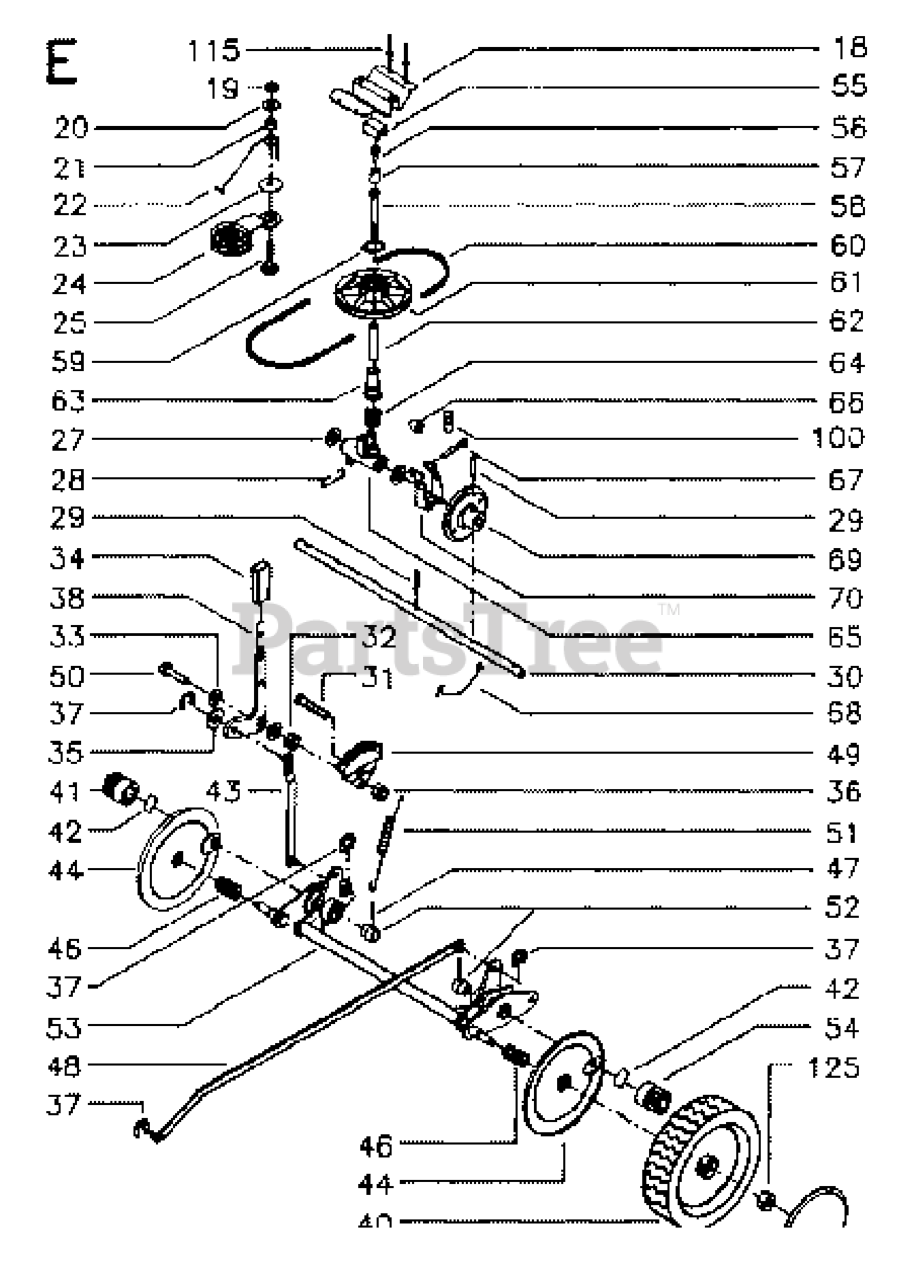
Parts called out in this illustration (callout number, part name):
1	DECK.WELDMENT.54"MS-498
6	COVER.MANDREL.LH.54"20
7	COVER.MANDREL.RH.54.20
8	BOLT.WASHER.ASM.7/16-2
11	BLADE.BAGGING.54"
12	ROD.ANTI.SWAY.48/54"K4
13	SHAFT ASM MANDREL
14	RP.HOUSING.MANDREL.4PT.
16	WASHER
18	BOLT
19	PIN.COTTER.5/16.BOW TI
21	LOCKNUT
24	CAP-SLEEVE LT
25	SPRING, TORSION
26	NUT PUSH M
27	DEFLECTOR
29	ROD.HINGE
30	SCREW, WASHER HEAD
31	WASHER.SPACER.MANDREL
32	PULLEY/MANDREL
33	NUT.FLANGE.LOCK.TOP
39	RB PULLEY.IDLER.4.50/HUB SPEC
43	ARM.IDLER
46	SCREW.1/4-20X5/8
47	RP.BELT.DRIVE.54."2006
49	NUT LOCK FLG 3/8-16 UNC
50	BOLT
52	PULLEY.IDLER.2006
58	BAFFLE.RIGHT.54"
59	BAFFLE.LEFT.54"
60	BAFFLE CENTER 54" MOWER
98	SPRING, DECK DRIVE
113	BOLT CRT
114	ROD TENSION RELIEF
116	BOLT.SHOULDER.3/8-16X3-5/8.
117	RP WHEEL. GUAGE RALLY
120	WASHER
122	BUSHING.RELIEF.TENSION
184	NUT LOCK HEX FLANGE 5/16-18
185	NUT.LOCK.FLANGE.7/16
187	STUD.FASTNER.W/ANTI-ROTATE
189	ARM.SUSPENSION.MOWER
190	BOLT.SHOULDER
192	KEEPER.BELT.IDLER.54"T
194	BOLT.HEX.WASHER.HEAD.7/16-24X
196	BOLT
241	SCREW.TT.#10-32X.5.3/8.FLANGE
242	PORT.WASHOUT
